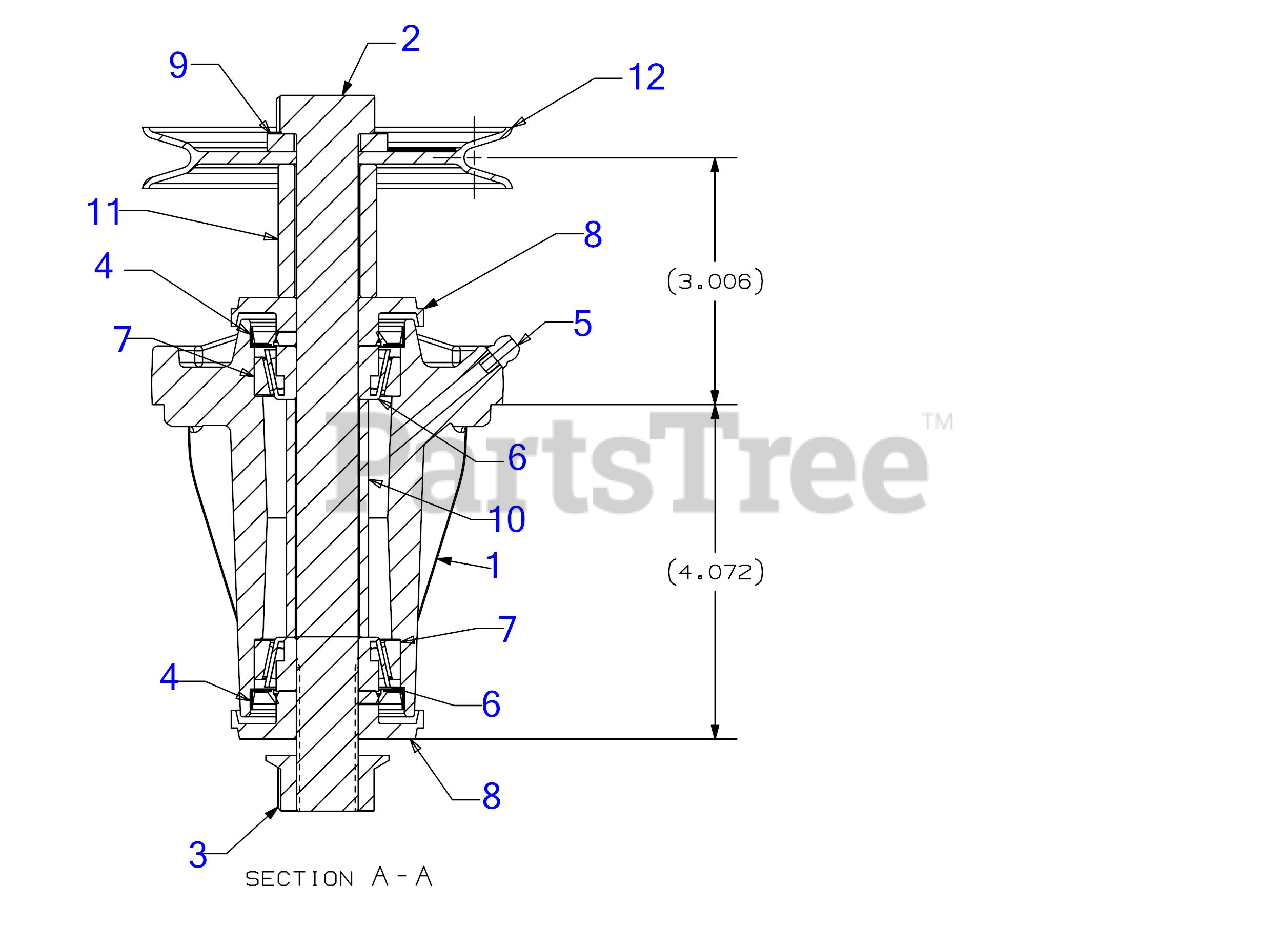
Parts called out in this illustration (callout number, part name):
1	SPINDLE HOUSING
2	SCREW 3/4-16 x 8.25 GR5
3	HEX FLANGE NUT 3/4
4	SINGLE LIP SEAL
5	GREASE FITTING
6	BEARING CONE
7	BEARING CUP
8	DECK SPINDLE SPACER
9	SPACER .812 ID x .218 LG
12	PULLEY-4.00 OD
